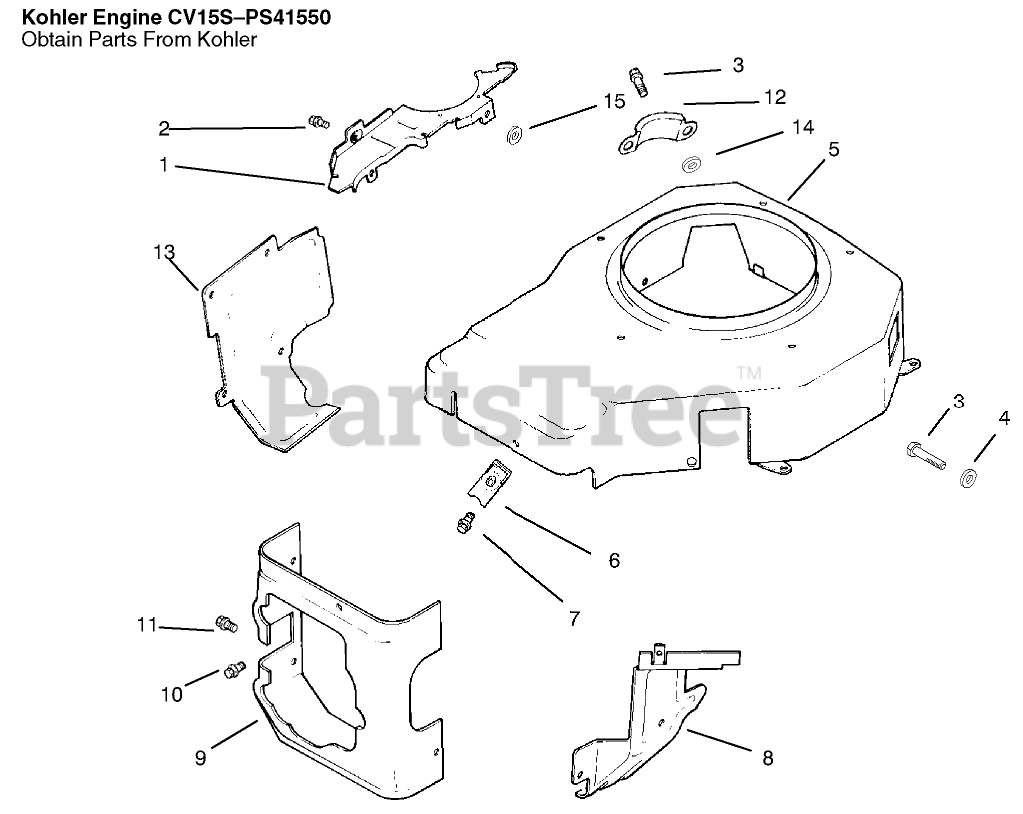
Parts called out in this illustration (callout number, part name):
1	Plate-Blower Housing
2	Screw
3	Screw
4	Washer
5	Housing-Blower
6	Clip
8	Baffle-Carburetor
9	Baffle-Cyl. Head
10	Screw
11	Screw
12	Cover-Pinion
13	Baffle-Cylinder
14	Washer
15	Washer
